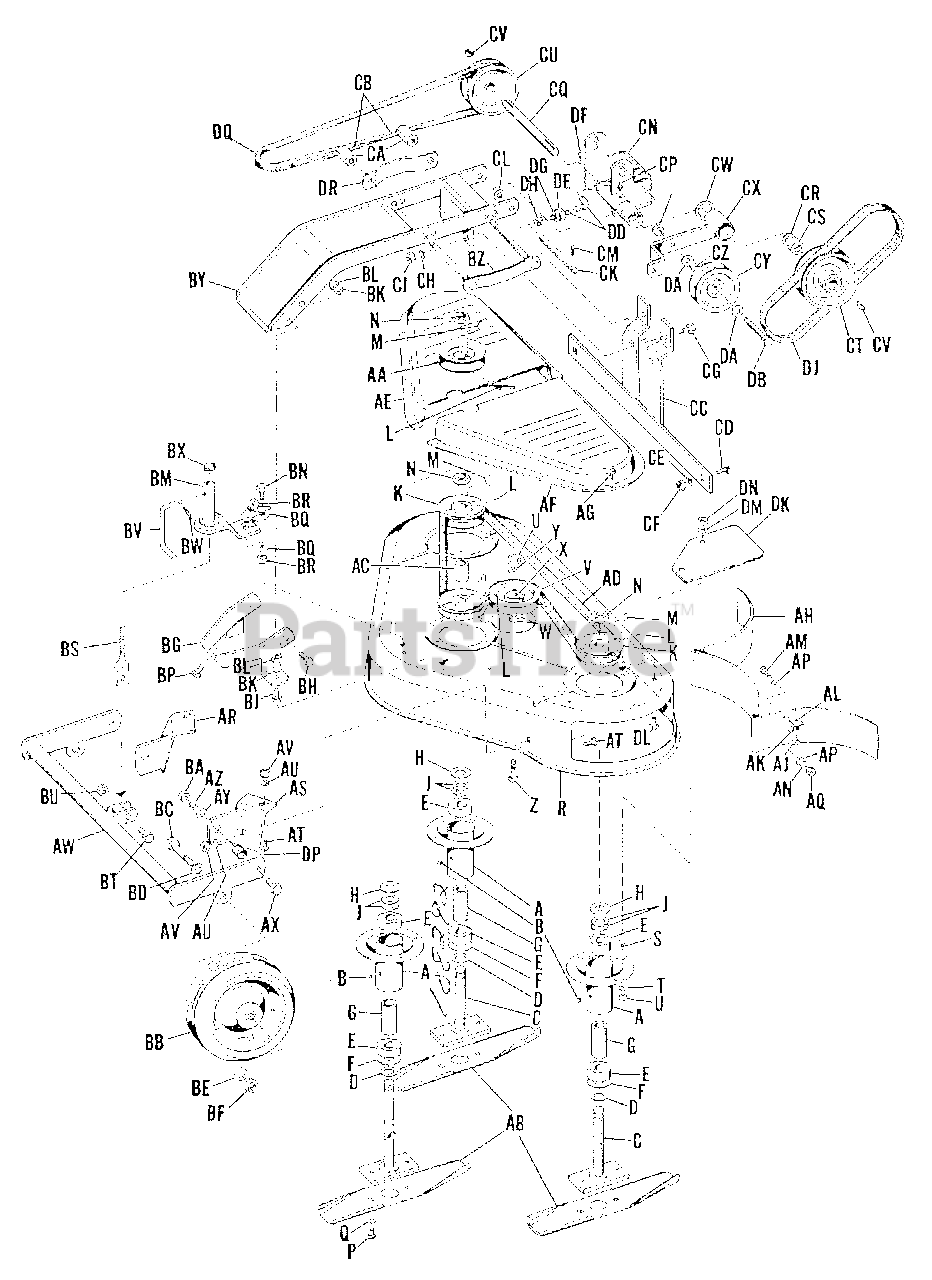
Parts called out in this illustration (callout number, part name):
A	ARBOR TUBE ASSEMBLY
B	PLUG, Pipe, 1/8"
C	ARBOR ASSEMBLY
E	BEARING, Radial
L	ARBOR ASSEMBLY
M	KEY, Woodruff, #61
N	NUT, Jam, Hex, 3/4"-16 NF
P	CAPSCREW, Hex, 3/8"-16 NC x 5/8" Lg.
Q	LOCKWASHER, 3/8"
S	CARRIAGE BOLT, 3/8"-16 NC x 3/4" Lg.
T	LOCKWASHER, 3/8"
U	NUT, Hex, Full, 3/8"-16 NC
V	PULLEY, Idler
W	WASHER, Plain, 5/16"
X	SIDE PLATE, Hitch
Z	CARRIAGE BOLT, 3/8"-16 NC x 1-3/4" Lg.
AA	PULLEY, Cross Drive
AD	BELT, "V", Spindle Drive
AE	COVER, Housing, R.H.
AF	COVER, Housing, L.H.
AG	SCREW, Self Tapping, Recessed Hex Head, 1/4"-20 NC x 3/8" Lg.
AH	BAFFLE, Mower
AJ	SCREW, Self Tapping, Recessed Hex Head, 1/4"-20 NC x 7/8" Lg.
AK	LOCKWASHER, 1/4"
AL	CLIP, Baffle
AM	CAPSCREW, Hex, 1/4"-20 NC x 5/8" Lg.
AN	LOCKWASHER, 1/4"
AP	WASHER, Plain, 1/4"
AQ	NUT, Hex, Full, 1/4"-20 NC
AR	BRACKET ASSEMBLY, Front, R.H.
AS	BRACKET ASSEMBLY, Front, L.H.
AT	CARRIAGE BOLT, 3/8"-16 NC x 3/4" Lg.
AU	LOCKWASHER, 3/8"
AV	NUT, Hex, Full, 3/8"-16 NC
AW	SUPPORT ASSEMBLY, Wheel
AX	CAPSCREW, Hex, 3/8"-16 NC x 1" Lg.
AY	WASHER, Plain, 3/8"
AZ	LOCKWASHER, 3/8"
BA	NUT, Hex, Full, 3/8"-16 NC
BB	WHEEL ASSEMBLY
BC	CAPSCREW, Hex, 1/2"-13 NC x 4-1/2"
BD	WASHER, Plain, 7/16"
BE	LOCKWASHER, 1/2"
BF	NUT, Hex, Full, 1/2"-13 NC
BG	YOKE ASSEMBLY, Crank
BH	CAPSCREW, Hex, 3/8"-16 NC x 3/4" Lg.
BJ	CAPSCREW, Hex, 3/8"-16 NC x 1" Lg.
BK	LOCKWASHER, 3/8"
BL	NUT, Hex, Full, 3/8"-16 NC
BM	BRACKET, Crank
BN	CAPSCREW, Hex, 3/8"-16 NC x 1-1/4" Lg.
BP	CAPSCREW, Hex, 3/8"-16 NC x 1" Lg.
BQ	LOCKWASHER, 3/8"
BR	NUT, Hex, Full, 3/8"-16 NC
BS	SCREW ASSEMBLY, Height Adjusting
BT	CAPSCREW, Hex, 3/8"-16 NC x 1-1/4" Lg.
BU	NUT, Hex, Full, Lock, 3/8"-16 NC
BW	PIN, Cotter, 3/32" x 3/4" Lg.
BX	PLUG, Button
BY	ARM ASSEMBLY, Push
BZ	CLAMP ASSEMBLY, Hitch
CB	BELT, "V", Cross Drive
CC	BRACKET ASSEMBLY, Rear
CD	CARRIAGE BOLT, 3/8"-16 NC x 1" Lg.
CE	LOCKWASHER, 3/8"
CF	NUT, Hex, Full, 3/8"-16 NC
CG	CAPSCREW, Hex, 3/8"-16 NC x 1" Lg.
CH	LOCKWASHER, 3/8"
CJ	NUT, Hex, Full, 3/8"-16 NC
CK	PIN, Pivot
CL	WASHER, Plain, 3/8"
CM	PIN, Cotter, 3/32" x 7/8" Lg.
CN	BRACKET ASSEMBLY, Drive
CP	FITTING, Grease, #1641 Alemite
CQ	SHAFT, Idler
CS	BEARING, Needle
CV	KEY, Woodruff, #9
CW	RING, Retaining
CX	LEVER ASSEMBLY, Idler
CY	PULLEY, Idler
DA	WASHER, Plain, 5/16"
DB	CAPSCREW, Hex, 3/8"-16 NC x 1-3/4"
DC	NUT, Hex, Full, 3/8"-16 NC
DE	NUT, Hex, Elastic, 3/8"-16 NC
DF	PIN, Cotter, 3/32" x 7/8"-Lg.
DG	WASHER, Plain, 5/16"
DK	DEFLECTOR
DL	CARRIAGE BOLT, 5/16"-18 NC x 3/4" Lg.
DM	LOCKWASHER, 5/16"
DN	NUT, Hex, Full, 5/16"-18 NC
